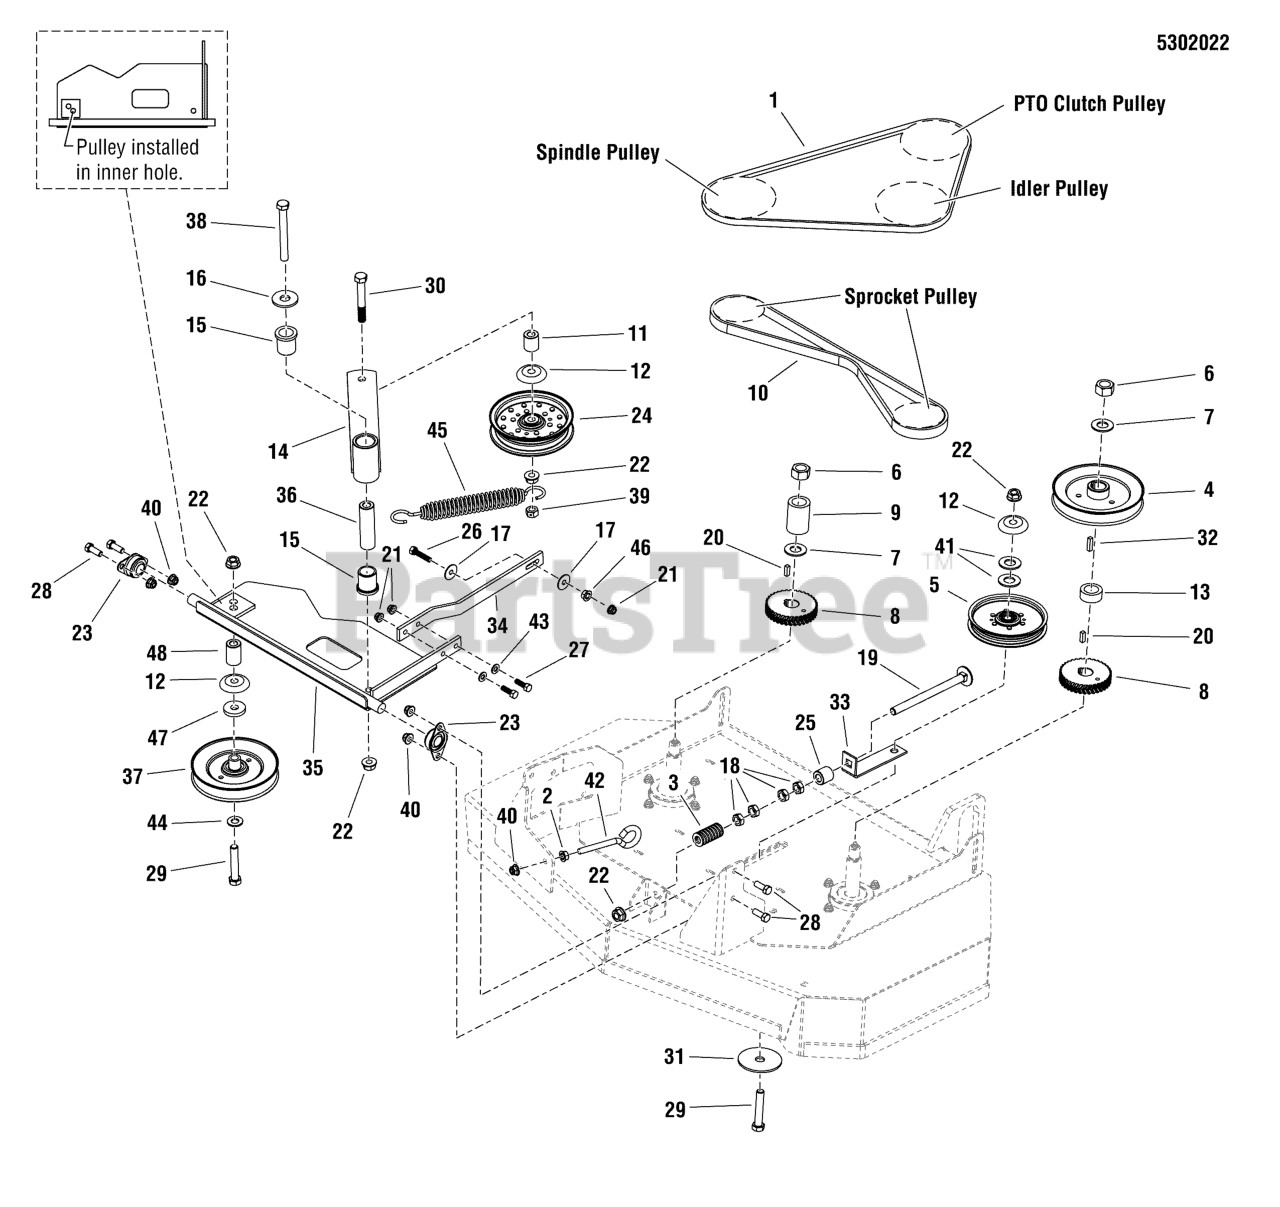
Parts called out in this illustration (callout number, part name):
1	BELT, BP-SEC, 91.12EL, ARAMID, WRPD
2	NUT, 3/8-16 HEX SERRATED FLANGE
3	SPRING, COMPRESSION 2 MEDIUM
4	PULLEY-6.122 OD. X .98 BORE X 1.53 HEIGH
5	PULLEY-IDLER, 5.00OD, .385ID, 1.50W STL
6	NUT, 3/4-16 HEX
7	WASHER, 3/4 BELLEVILLE
8	SPROCKET, GOODYEAR EAGLE PD
9	SPACER, 1.00 X 1.57 X 2.19
10	BELT, SPROCKET DRIVE
11	SPACER, .52 X 1.00 X 1.15
12	SHIELD, PULLEY BEARING
13	SPACER, 1.00 ID X 1.50 OD X .63 LG. YZ.
14	WELD, IDLER ARM - RED
15	BUSHING, FLANGE
16	WASHER, 5/8 USS
17	WASHER, 5/16 FENDER
18	NUT, 1/2-13 HEX JAM
19	BOLT, 1/2-13 X 7, CARRIAGE
20	KEY, 1/4 SQ. X 3/4
21	NUT, 5/16-18 HEX NYLOCK FLANGE
22	NUT, Hex Flange, Nylock, 1/2-13
23	BEARING, BRONZE FLANGE, 3/4"
24	PULLEY, IDLER, 5" OD, 1"FACE, 5.75 FL
25	SPACER, .515 X 1.00 X 1.00, YZ
26	BOLT, 5/16-18 X 1-1/2 GD5 YZ
27	BOLT, 5/16-18 X 1 GD5 YZ
28	BOLT, 3/8-16 X 1" GD5 CZ
29	BOLT, 1/2-13 X 2-3/4 GD5 CZ
30	BOLT, 1/2-13 X 3-1/2, HEX HD, GD5, CZ (SV)
31	WASHER, .64 X 3.00 X .14, YZ
32	KEY, 1/4 SQ. X 1.25
33	PLATE, BRACKET, IDLER - RED
34	BAR, IDLER PLATE SUPPORT - RED
35	WELD, IDLER MOUNT PLATE - RED
36	SPACER, .52 X 1.00 X 3.50
37	PULLEY, 6" DEEP GROOVE, COMPENSATOR
38	BOLT, 1/2-13 X 4-1/2 GD5
39	NUT, 1/2-13 HEX SIDE LOCK
40	NUT, 3/8-16 HEX NYLOCK FLANGE
41	WASHER, 1/2 SAE
42	EYEBOLT, 3/8-16 X 4, 2.13THRD, .75EYE, C
43	WASHER, 5/16" SAE
44	WASHER, 1/2 SAE
45	SPRING, EXTENSION, SWIVEL, SHORT HOOK
46	NUT, 5/16-18 HEX SERRATED FLANGE (SMALL)
47	SPACER, .52 X 1.00 X .22, PM, CZ
48	SPACER, .52 X 1.00 X .75
